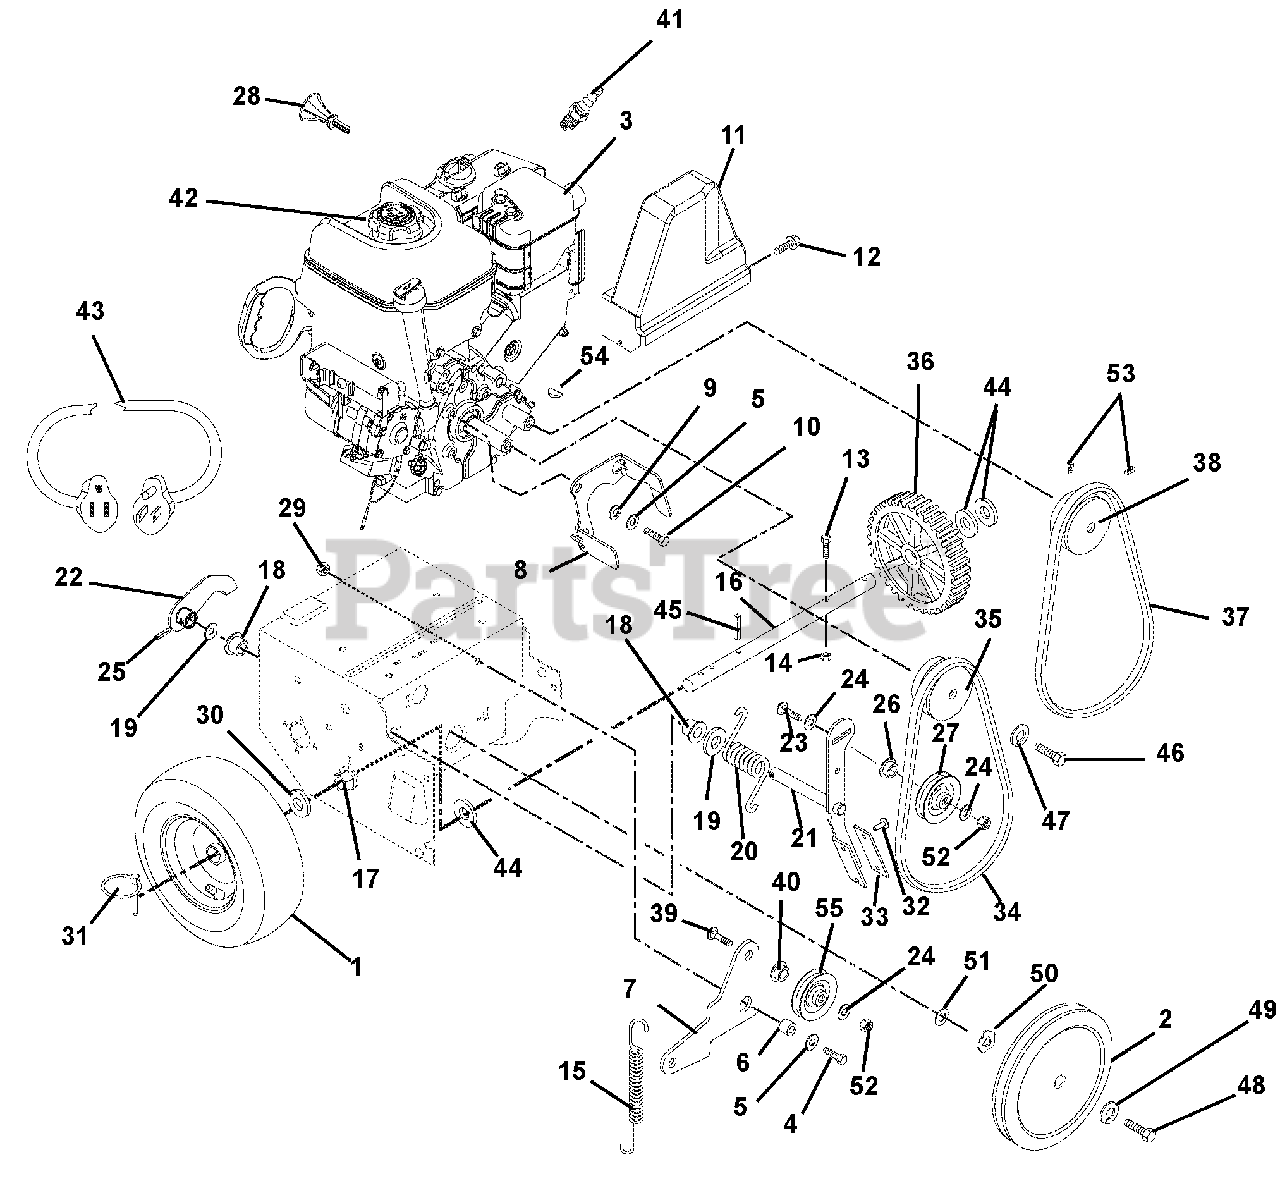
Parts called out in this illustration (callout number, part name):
1	TIRE/WHEEL, LH 13X4.00-6 PIN
1	TIRE/WHEEL, RH 16X6.50-8 DIFF
1	TIRE, 2PR X-TRAC TL 13X4.00-6
1	WHEEL, 4.1-6
2	PULLEY, 3L W/HUB, .625 X 8.0
3	ENGINE,5.5HP 120V PWRBILT SNOW
4	@BLT-HEX .31-18X.75 GR5 YWZC
5	@WSHR-FL-STL.38X.875X.083 YWZC
6	SPACER BUSHING .5 X .32 X .163
7	IDLER ARM
8	FINGER, BELT
9	WSHR-LK .312X.097 HVY YWZC
10	BLT-HEX .31-24X1.0 GR5 YZ EP80
11	BELT COVER
12	@SCR-TAP .25-20X.37 HWH YWZ TR
13	BLT-HEX .25-20X1.75 GR8 YWZC
14	@NUT-LK-CTR .25-20 YWZC
15	SG-TENS .047X.44X3.37 WLD 1.47
16	AXLE SHAFT, COMPACT W/PIN LOCK
17	BSHG-FLG .750X.873HEXX.53X1.18
18	BSHG-FLG .500X.625X.500X.750
19	WSHR-FL-STL .520X.810X.033YWZC
20	SG-TORS .148X1.0X1.53
21	CLUTCH ARM W/BRAKE PAD
22	ARM-CLUTCH
23	@BLT-RHDSHSQNK.31-18X1.25 G5YZ
24	@WSHR-FL-STL.38X.875X.083 YWZC
25	PIN-ROLL .156X.88
26	SPCR, BRG .315X.50X.688X.281
27	IDLER
28	KEY, IGNITION PUSH/PULL B&S
29	@NUT-LK-CTR .31-18 YWZC
30	WSHR-FL-STL.754X1.125X.062YWZC
31	PIN-LOK .31X1.75
32	RVT-TBLR .187X.437 RH ST PL
33	BRAKE LINING
34	BELT,4L TO BE REPLACED07200021
35	SHEAVE, ENGINE
37	V-BELT, 3L-COGGED
38	SHEAVE - CAMSHAFT
39	@BLT-RHDSHSQNK.31-18X1.25 G5YZ
40	BSHG-FLG .320X.671X.575X.895
41	PLUG, SPARK
42	CAP, FUEL - BRIGGS
43	CORD, ELECTRIC START CORD 120V
44	WSHR-FL-STL .755X1.25X.125 YZ
45	PIN-ROLL .188X1.25
46	BLT-HEX .38-24X1.0 GR5 YZ EP80
47	@WSHR-LK .38X.094 REG YWZC
48	BLT-HEX .25-28X.75 GR5 YZ EP80
49	WSHR-LK .250X.077 HVY YWZC
50	WSHR-WAVE .69X.84X.011
51	WSHR-THRST .625 X 1.0 X .03
52	@NUT-LK-CTR-JAM .31-18 YWZC
53	SCR-SET .31-18X.38 SKHCUPDL
54	KEY-WDRF .125X.625X.250 SAE5
55	IDLER-FLAT 1.75"X .670 PLASTIC
